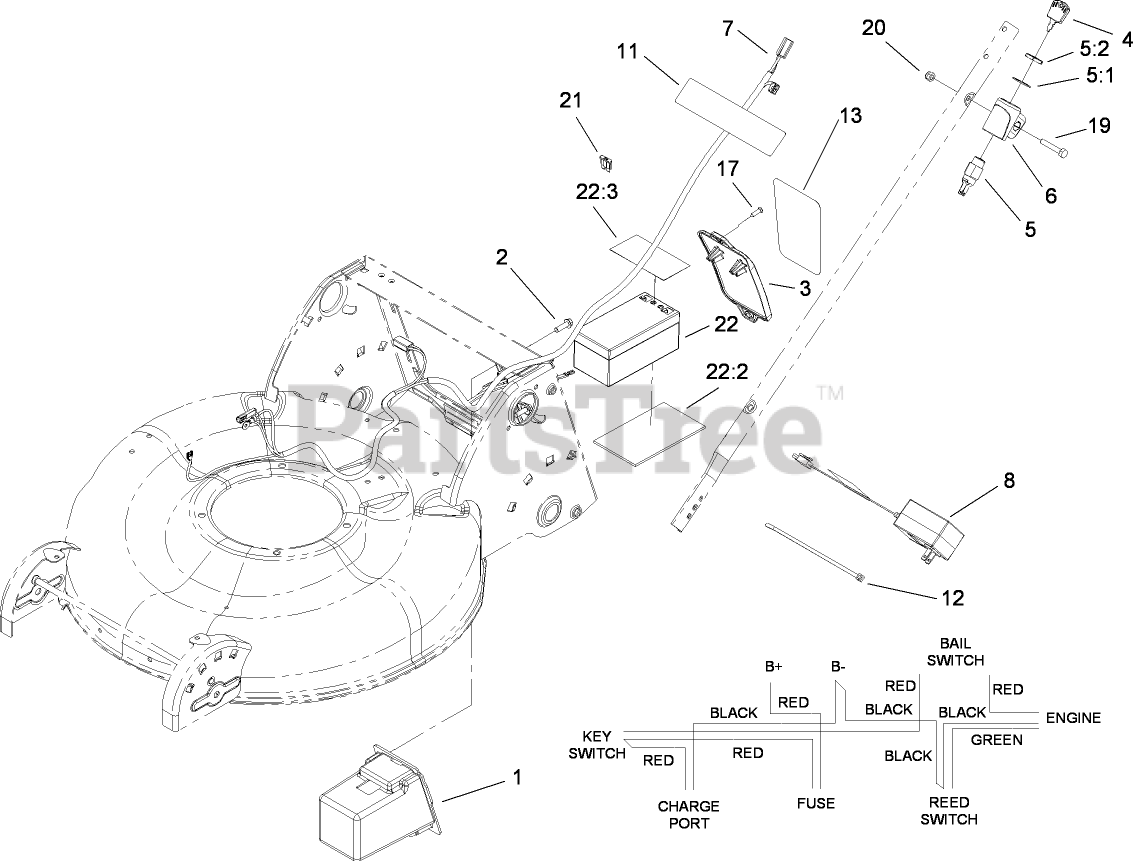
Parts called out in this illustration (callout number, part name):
1	BOX-BATTERY
2	SCREW-HWH
3	COVER-BATTERY
5	STARTER SWITCH ASM
5:1	WASHER-LOCK
6	MOUNT-SWITCH
7	HARNESS-WIRE
8	CHARGER-EUROPEAN, 12V DC
11	DECAL-WARNING
12	TIE-CABLE
13	DECAL-INSTRUCTION, BATTERY
17	SCREW-PPH
19	SCREW-HH
20	NUT-LOCK, NI
21	FUSE-40 AMP
22	BATTERY-WET
22:2	FOAM-BATTERY
22:3	DECAL-TERMINAL, BATTERY
